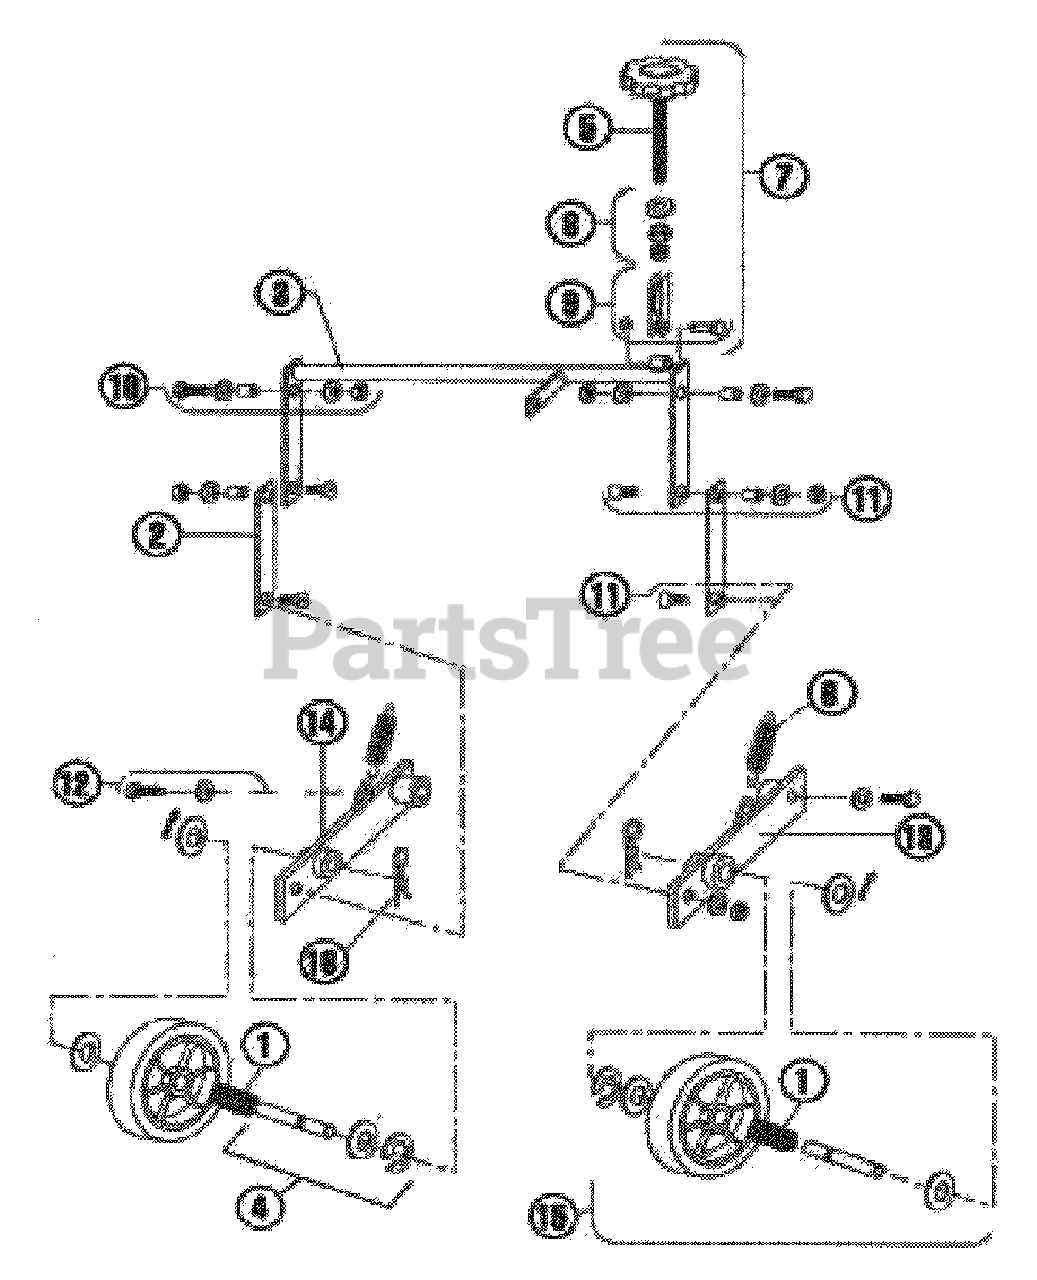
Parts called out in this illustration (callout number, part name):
1	Bearing, roller with seals
3	Torque arm, depth adjustment
4	Axle kit, axle, E-clip, 2 washers, cotter pin, hairpin cotter
5	Knob, depth/stability
6	Spring, axle
7	Control kit, depth/stability
8	Knob spring kit, depth/stability
9	Bracket kit, depth/stability
10	Fastener kit, torque arm/housing
11	Fastener kit, linkage
12	Fastener kit carriage/housing
13	Wheel arm right
14	Wheel arm left
15	Wheel assembly wheel, bearing, 2 seals, axle, 2 washers, E-clip, cotter pin, hairpin cotter
16	Cotter key, hairpin
